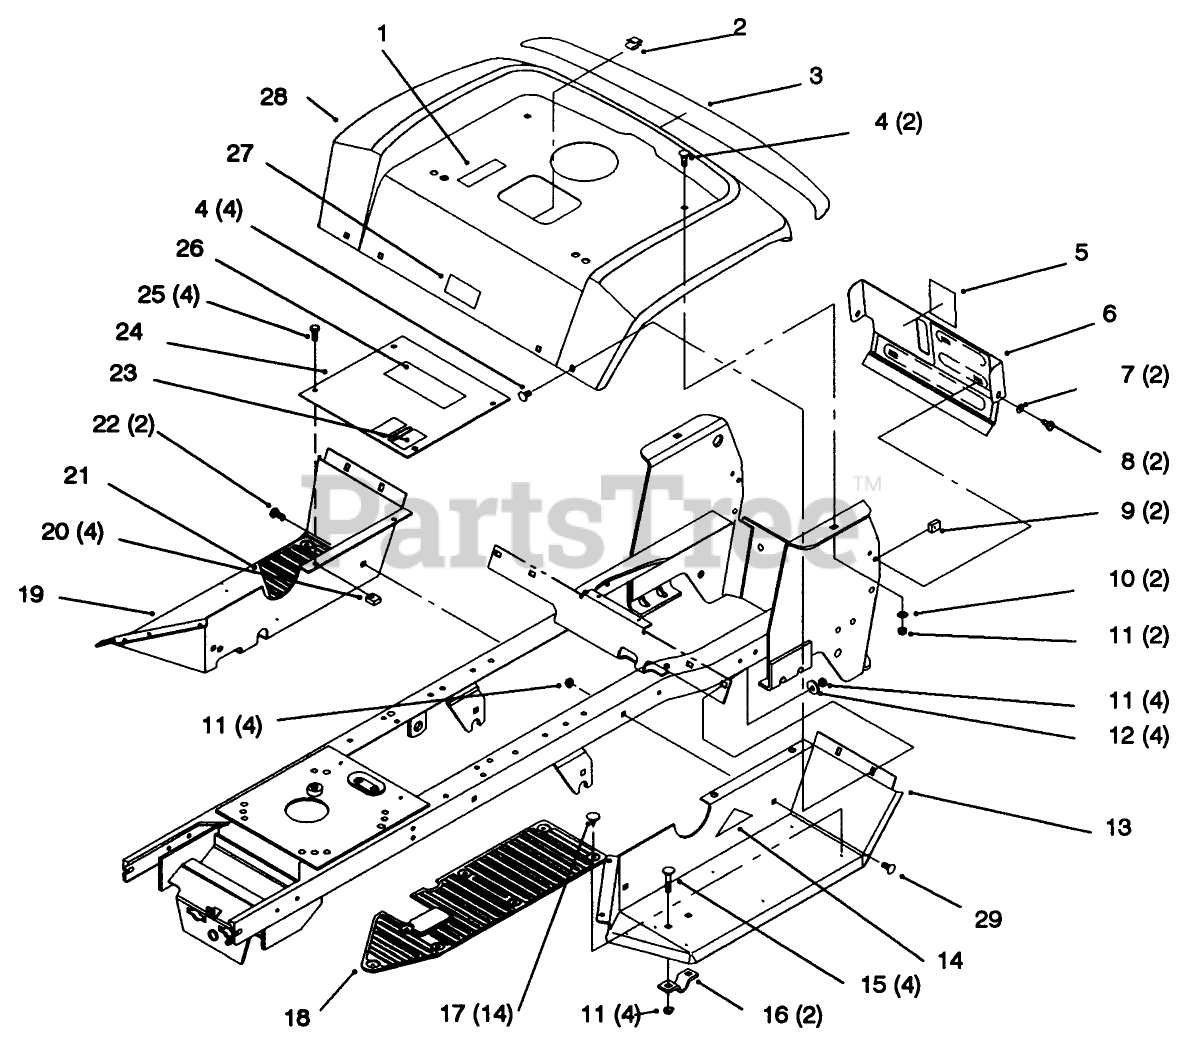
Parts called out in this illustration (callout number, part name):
2	CLIP-RETAINER, WIRE
3	DECAL - REAR FENDER
4	BOLT-CARR
5	DECAL-LEVEL, FUEL
6	Rear Panel
7	WASHER-FLAT
8	SCREW-HH
9	NUT-SPEED
10	WASHER-PLAIN
11	NUT-LOCK, NI
12	WASHER
16	CLAMP
17	FASTENER-PANEL
18	FOOTPAD-LH
19	FOOTREST-RH
21	FOOTPAD-RH
22	SCREW-CARR
23	DECAL - HOC
24	PLATE/DECAL ASM-FOOTREST
25	SCREW-HH
26	DECAL-DANGER
27	DECAL - USA
29	SCREW-CARR
